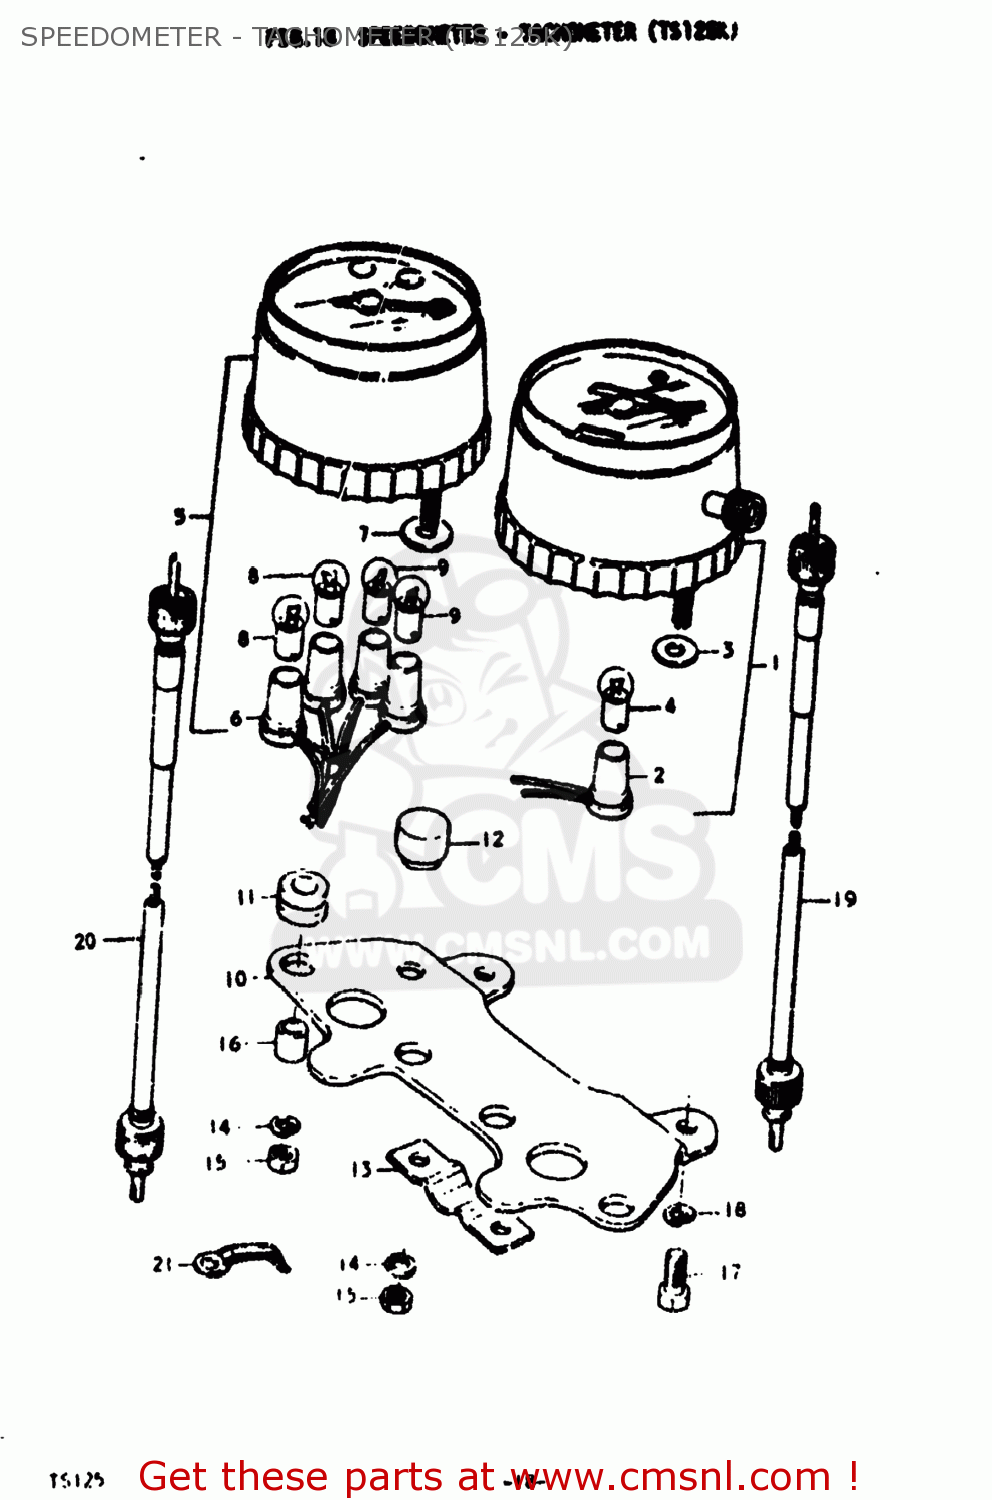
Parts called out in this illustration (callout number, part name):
1	SPEEDOMETER ASSEMBLY
2	SOCKET,METER
3	WASHER (6.5X13X2.3)
4	BULB(6V/3W)
5	TACHOMETER ASSEMBLY
6	SOCKET,TACHOMETER
7	WASHER (5.5X16X1.2)
8	BULB(6V/3W)
9	BULB(6V1.7W,STANLEY,A61A)
10	BRACKET,METER
11	CUSHION
12	CUSHION,METER
13	COVER,METER,UNDER
14	LOCK WASHER
15	NUT
16	SPACER,METER NO.2
17	BOLT
18	LOCK WASHER
19	CABLE ASSY,SPEEDOMETER
20	CABLE ASSY,TACHOMETER
21	CLAMP
